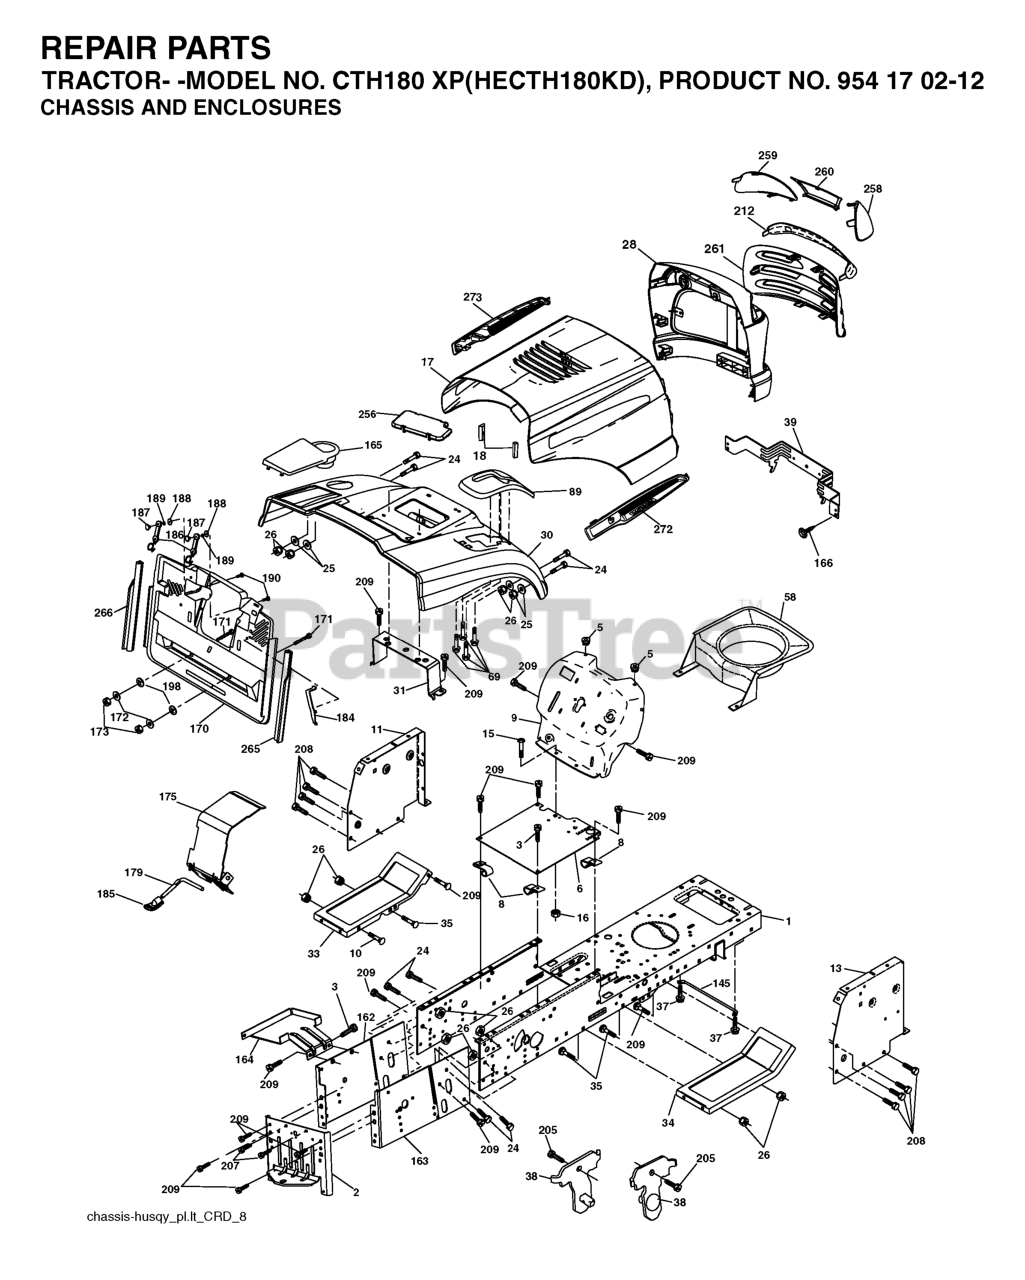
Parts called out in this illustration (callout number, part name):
2	DRAWBAR
3	SCREW 3/8-16X3/4
5	BUMPER.RUBBER.HOOD
6	PLATE
8	CLIP,INSULATOR
9	DASH.SLK.PL.CRD.NA
10	BOLT D
11	PANEL.DASH.LH.LTX
13	PANEL ASM, DASH RH
15	Screw, Machine, Truss Head 5/16-18 UNC x 3/4
16	NUT
17	VENT.HOOD.LASER.III
18	BUMPER.HOOD.LARGE.1.75"
25	WASHER
26	NUT
31	BRACKET SUPPORT FENDER
33	FOOTREST PNT LH
34	FOOTREST PNT RH
37	Screw 5/16-18 x 1/2 Hex, Self Tapping 5/16-18 x 1/2
38	BRACKET ASM PIVOT MOWER REAR
39	BRACKET PIVOT LASER
69	SCREW.HI-LO.CONSOLE
89	COVER.BATTERY.CRD.GREY
145	ROD PIVOT CHASSIS/HOOD
162	BRACKET
163	BRACKET EXTEN CHASSIS RH CRD
165	RP.COVER.BATTERY.CRD.GREY
166	SCREW
172	WASHER
175	DOOR TRAP
179	ROD PIVOT FBI
184	BRACKET.ACTUATOR.BAGGER.SRD
186	LATCH ASSY
187	WELDNUT
189	LOCKWASHER #10
190	SCREW
207	SCREW, 5/16-18 X 1/2
208	SCREW 3/8-16X1/2
209	SCREW, 3/8-16X3/4
212	INSERT.LENS.REFLECTIVE
256	COVER FENDER CRD
258	LENS LH
259	LENS LH
260	COVER.LENS.HUSQ.LASER
265	SEALING
266	SEALING
272	VENT.HOOD.LASER.
273	VENT.HOOD.LASER.
